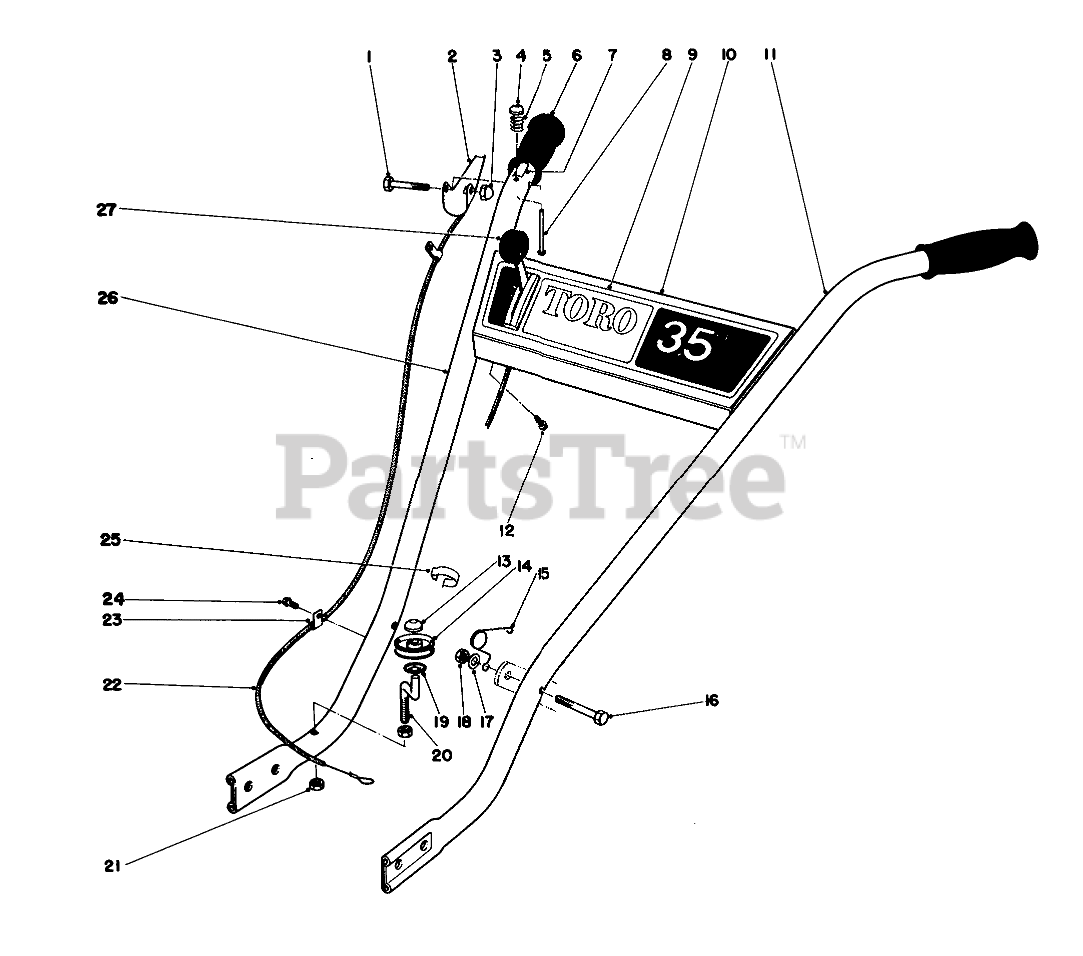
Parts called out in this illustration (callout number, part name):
1	SCREW-HH
2	LIFTBAIL
3	NUT-CAP
4	Push-On
5	COMPRESSION SPRING
6	Hand Grip
7	Decal-Fwd.
8	LOCK PIN
9	Decal-Escutcheon
10	Escutcheon Panel
11	L.H. Handle
12	SCREW-HWHTF
13	RETAINER PUSH ON
14	Pulley Cable
15	Spring-Torsion
16	SCREW-HH
17	WASHER-PLAIN
18	NUT-LOCK, CONE
19	PUSH ON RETAINER
20	Spindle-Fwd.
21	LOCKNUT
22	FWD CABLE ASM
23	3/16 SUPPORT
24	10 X 1/2 SCREW
25	Boden Clip
26	RH HANDLE
27	Throttle Control
